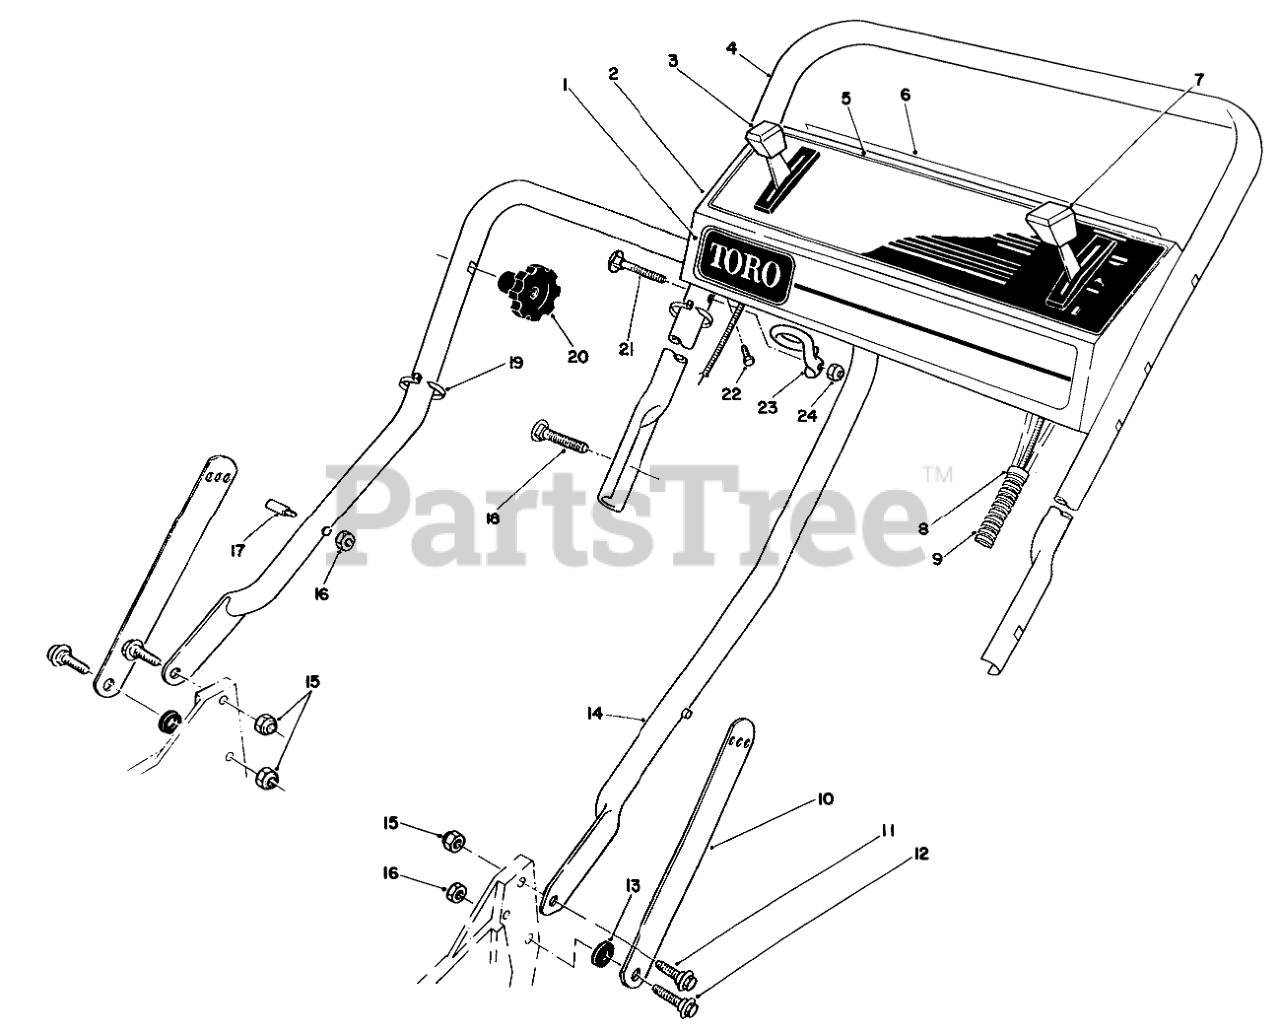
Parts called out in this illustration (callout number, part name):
1	DECAL - TORO PANEL
2	Panel-Control (Incl. Ref. #5)
3	Control-Ground Speed
4	UPPER HANDLE
5	DECAL - INSTRUCTIONS
6	DECAL - PANEL, REAR
7	THROTTLE CONTROL
8	FITTING-RING
9	CONTROL CABLE COVER
10	Handle Latch
11	SCREW-SHOULDER
12	SCREW-SHOULDER
13	SPACER
14	LOWER HANDLE ASM
15	NUT-LOCK, NI
16	NUT-LOCK, NI
17	HANDLE PIN
18	5/16-18 X 2 HNDLE SCREW
19	TIE-CABLE
21	HANDLE SCREW
22	SCREW-HWHTF
23	Guide
24	NUT-LOCK, NI
